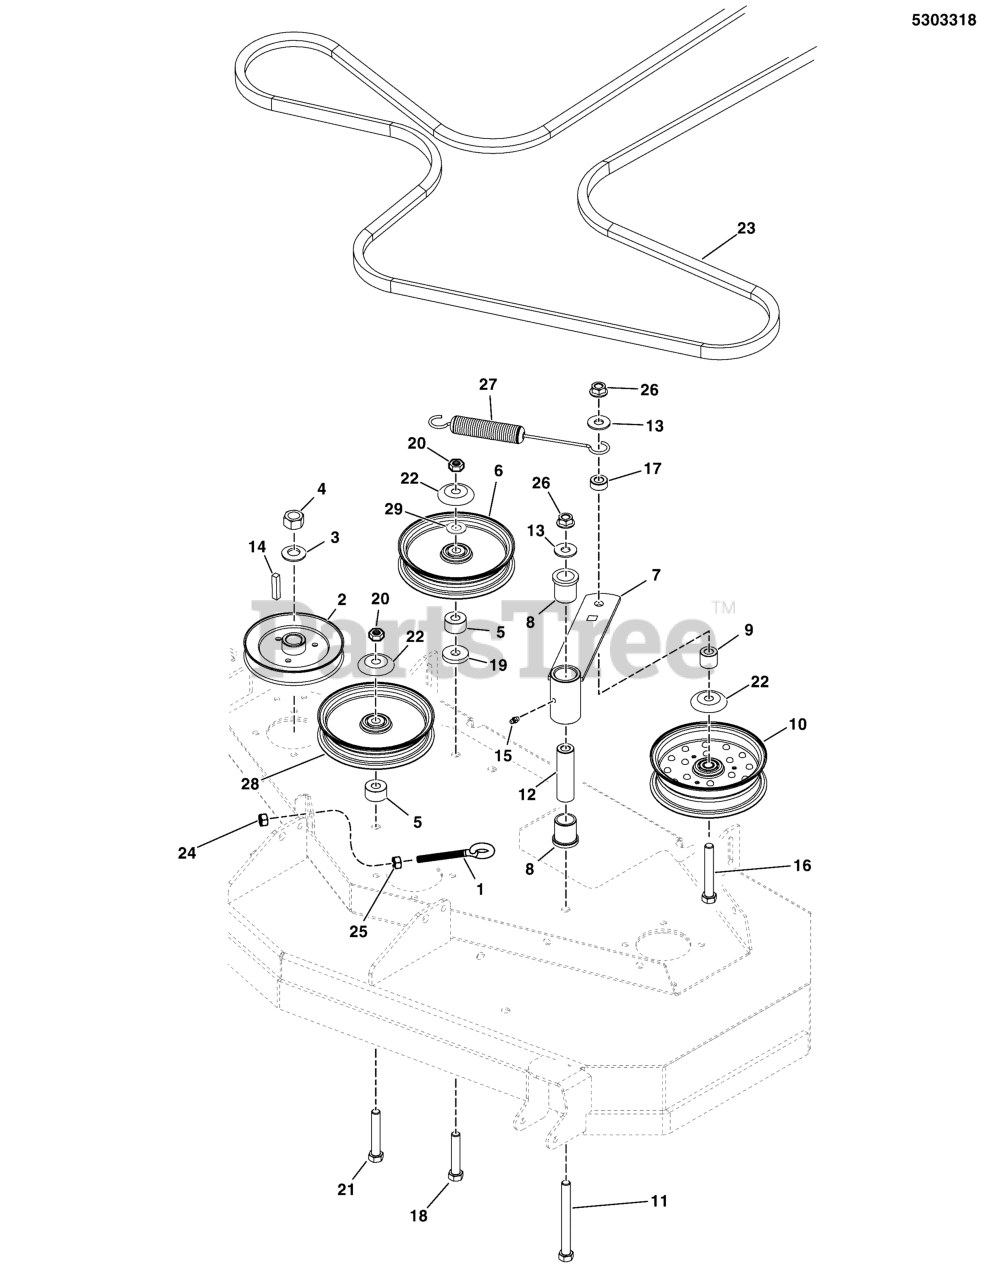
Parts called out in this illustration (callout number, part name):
1	EYE BOLT, 3/8-16 X 6, 3THRD, 1EYE, CZ
2	PULLEY, 5.540OB X .985ID, SINGLE B-SEC
3	WASHER, 3/4 BELLEVILLE
4	NUT, 3/4-16 HEX
5	SPACER, .52 X 1.25 X .70, CZ
7	WELD, IDLER ARM - BLK
8	BUSHING, FLANGE
9	SPACER, .52 X 1.00 X .88, CZ
11	BOLT-1/2-13 X 5 GD5 YZ
12	SPACER, .52 X 1.00 X 3.50
13	WASHER, 1/2 USS
14	KEY, 1/4 SQ X 1-1/4
15	GREASE FITTING, 1/4-28 STRAIGHT
16	BOLT, 1/2-13 X 3-1/2, HEX HD, GD5, CZ (SV)
17	SPACER, .52 X 1.00 X .44, CZ
18	BOLT, 1/2-13 X 2-3/4 GD5 CZ
19	WASHER, .53 X 1.50 X .25
20	NUT, 1/2-13 HEX SIDE LOCK
21	BOLT, 1/2-13 X 2-1/2" GD5 CZ
22	SHIELD, PULLEY BEARING, CZ
23	BELT, B-SEC, 136" EL, ARAMID, WRPD
24	NUT, 3/8-16 HEX NYLOCK FLANGE
25	NUT, 3/8-16 HEX JAM
26	NUT, 1/2-13 HEX NYLON LOCK
27	SPRING-EXT, 1.04 ODX10.535LGX.148WR, BLK
28	PULLEY, IDLER, 5" OD, 1"FACE, 5.75 FL
29	WASHER, 1/2 SAE
